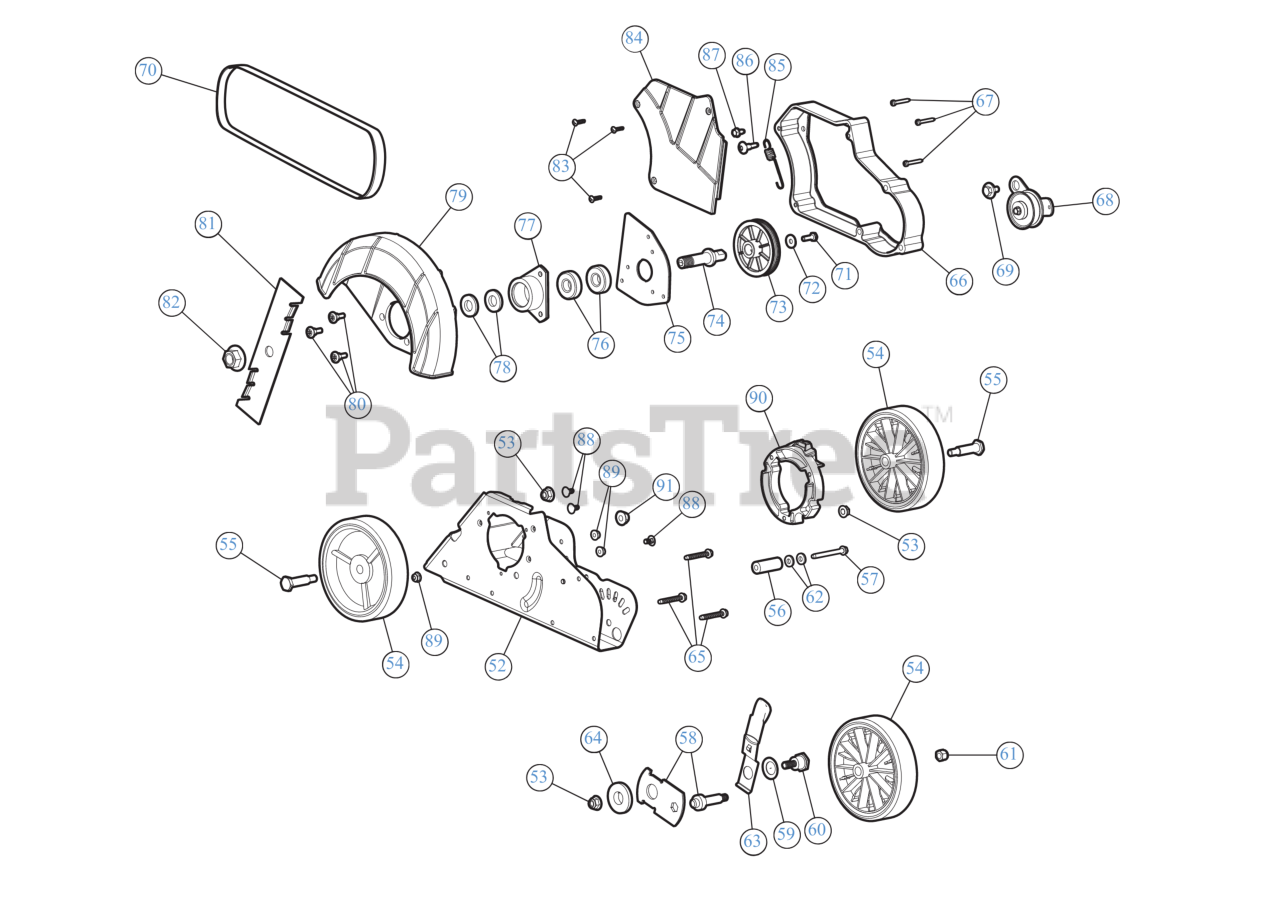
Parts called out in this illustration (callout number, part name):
54	WHEEL 5-1.5 GRAY
55	SHOULDER SCREW
56	SPACER
57	SCREW 1/4-20 x 2.375
58	PIVOT ARM
59	BELL WASHER
60	SHOULDER SCREW .75 X.50 X3/8-16
61	HEX NUT INS L-3/8-16
62	SPACER
63	HEIGHT LEVER ASSEMBLY
64	HEIGHT ADJUSTMENT BEARING
65	SCREW 1/4-20 x 1.750
66	SPACER
67	SCREW 8-16X1.25
68	IDLER PULLEY ASSEMBLY
69	SHOULDER SCREW .560X.165: 5/16-18
71	SCREW 1/4-20X.75 GR5
72	SPRING WASHER BELL
74	BLADE SPINDLE
75	SPINDLE MOUNT PLATE
76	BALL BEARING
77	BEARING CUP
78	FLAT WASHER .635 x 1.24 x .181
79	EDGER BLADE GUARD (W/LABEL)
80	SHOULDER SCREW .375X.280:1/4-14
81	EDGER BLADE
82	HEX NUT
83	SCREW 8-16 x 3/4
84	BELT COVER
85	SPRING
86	BOLT 1/4-20
87	SCREW 1/4-20 X.500
88	CARRIAGE BOLT 1/4-20X.50"
89	FLANGE LOCK NUT
90	SPACER
